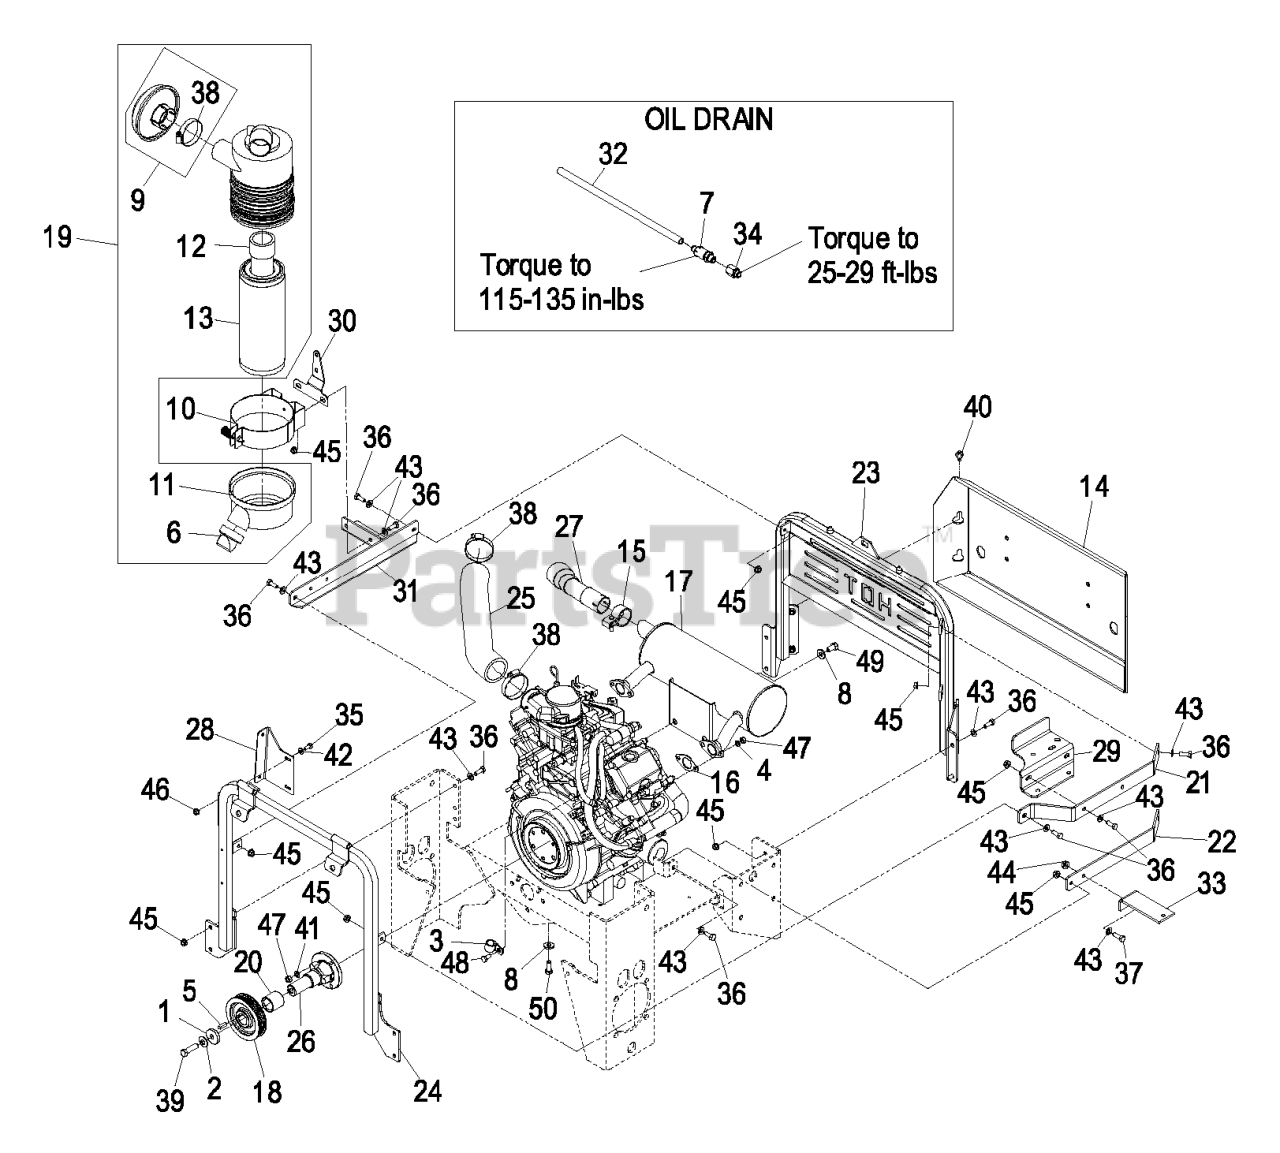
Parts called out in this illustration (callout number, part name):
1	WASHER-CLUTCH
2	WASHER-SPRING
3	CLIP-LOOM
4	WASHER-LOCK
5	KEY-SQUARE
6	VALVE-VACUATOR
7	VALVE-DRAIN, OIL
8	WASHER-BELLEVILLE
9	HOOD-CLEANER, 2" AIR INTA
10	BRACKET-FILTER, AIR
11	COVER-FILTER, AIR
12	FILTER-AIR, SAFETY
13	FILTER-AIR
14	WLD,REAR BUMPER
15	CLAMP-MUFFLER
16	GASKET-EXHAUST
17	KIT,MUFFLER
18	SHEAVE,5K 4"PD POLY-V
19	FILTER-AIR
20	SPACER,ENGINE SHEAVE
22	RIB, BOTTOM
24	ASM, RAD. MOUNT W/ DECALS
26	SHAFT, STUB
28	BRACKET,FRONT COVER
29	BRACKET,BOTTLE
30	BRACKET,REAR COVER
31	ASM,AIR CLNR BRKT W/ DECA
32	TUBE-DRAIN, OIL
33	BRACKET, HYDRAULIC TANK
34	ADAPTER
35	SCREW-HH
36	SCREW-HH
37	SCREW-HH
38	CLAMP-HOSE
39	SCREW-HH
40	SCREW-HHF
41	WASHER-LOCK
42	WASHER-FLAT
43	WASHER-PLAIN
44	NUT-HHF, WHIZ
47	NUT-HEX
48	SCREW-HH
49	SCREW-HH
50	SCREW-HH
